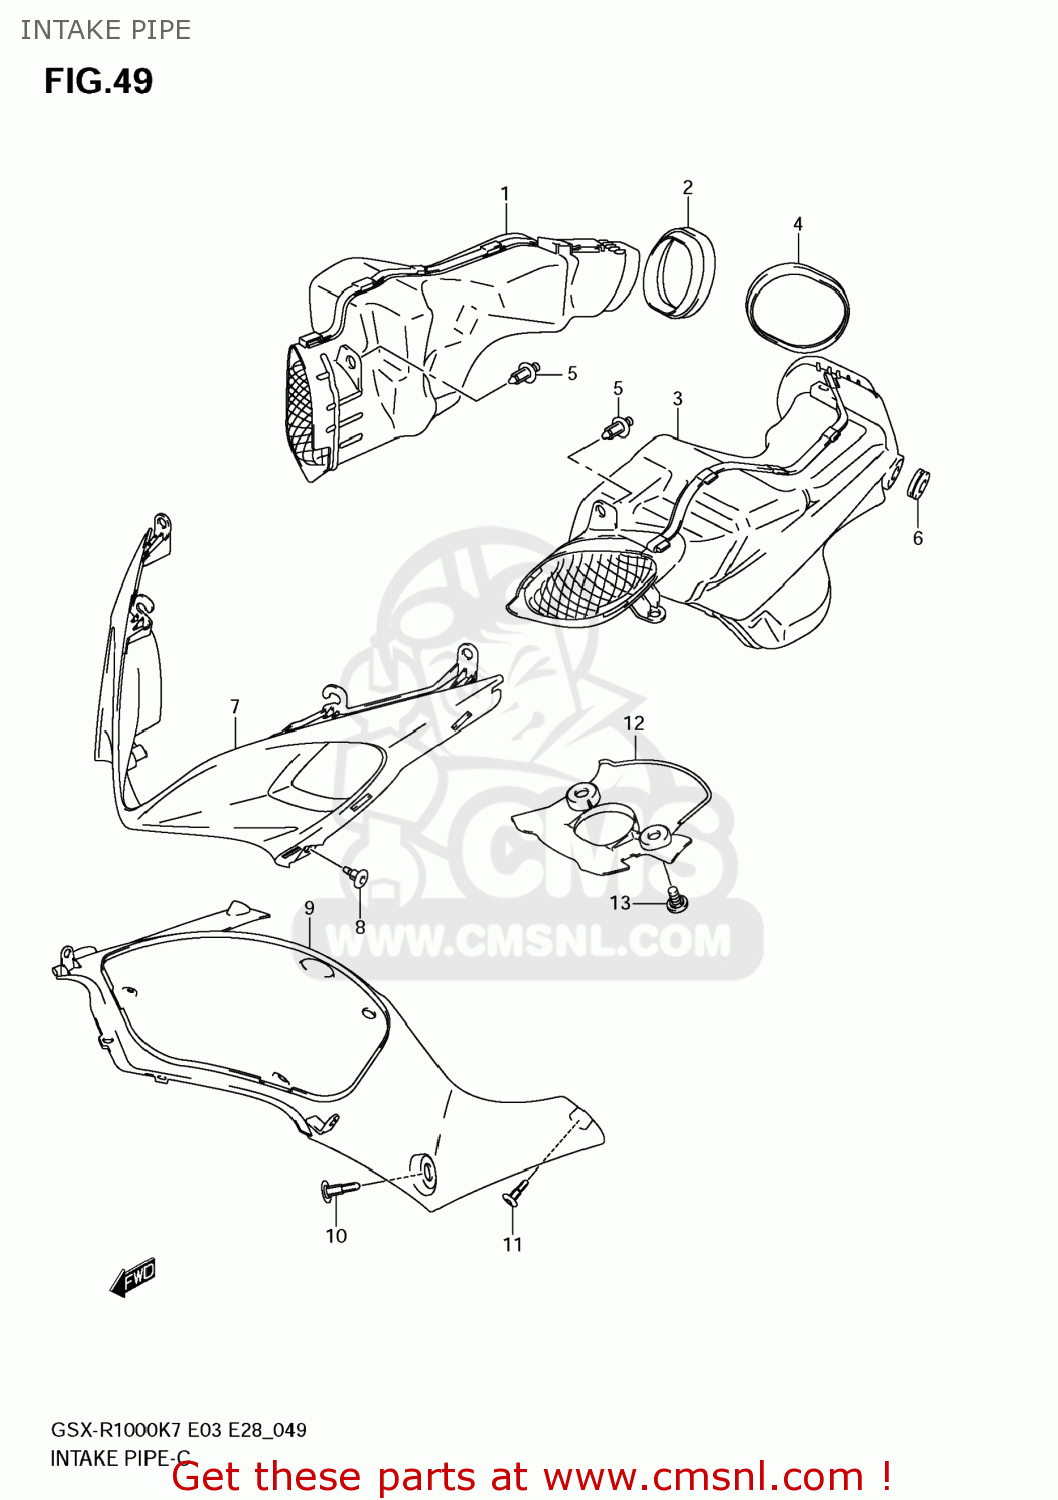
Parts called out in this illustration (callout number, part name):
1	PIPE,AIR INTAKE,R
2	MOLDING,AIR INTAKE,R
3	PIPE,AIR INTAKE,L
4	MOLDING,AIR INTAKE,L
5	CLIP(BLACK)
6	CUSHION
7	COVER,INTAKE(BLACK)
8	CLIP(BLACK)
9	COVER,BODY COWLING
10	CLIP(BLACK)
11	CLIP(BLACK)
12	COVER,LWR BRACKET
13	BOLT
